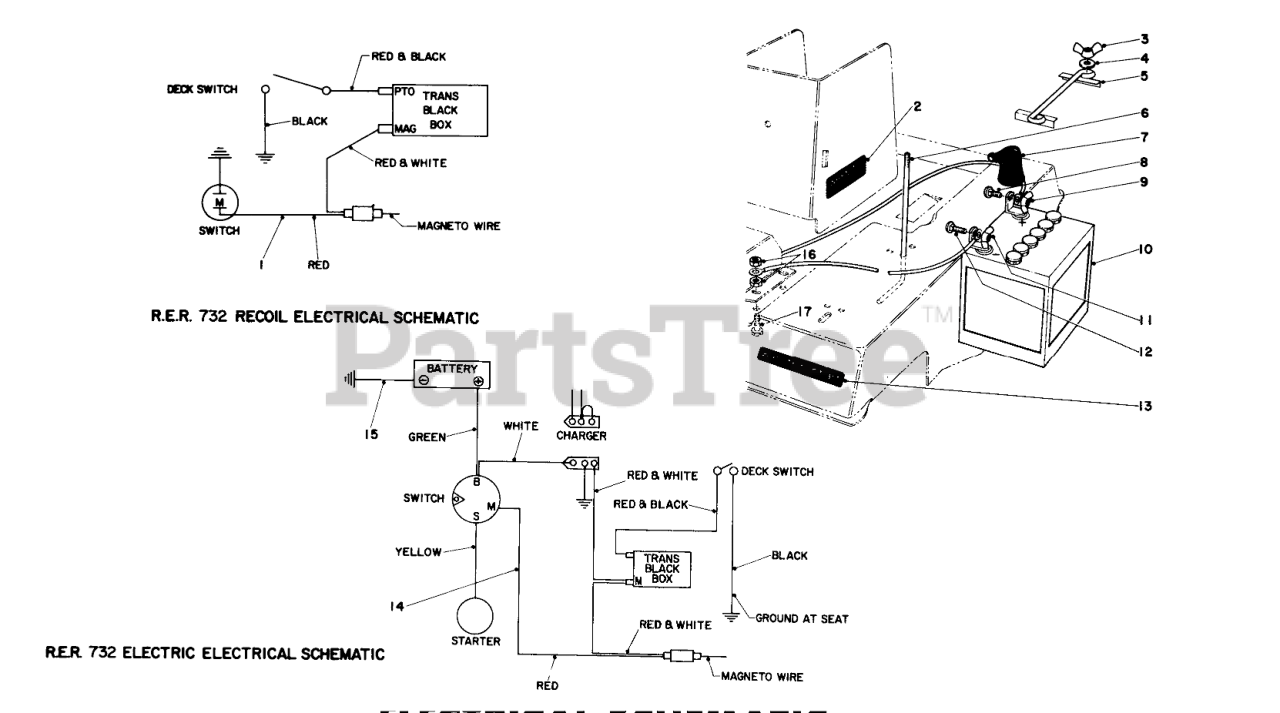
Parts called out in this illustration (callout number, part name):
1	Wire Harness
2	Decal (Model 56010)
3	Wing Nut
4	WASHER-FLAT
5	Clamp
6	Battery Bolt
7	BATTERY BOOT
8	BOLT-CARR
9	NUT-HEX
10	Battery
11	NUT-HEX
12	BOLT-CARR
13	Decal (Model 56150)
14	Wire Harness
15	Wire Assembly
16	NUT-LOCK, CONE
17	SCREW-HH
